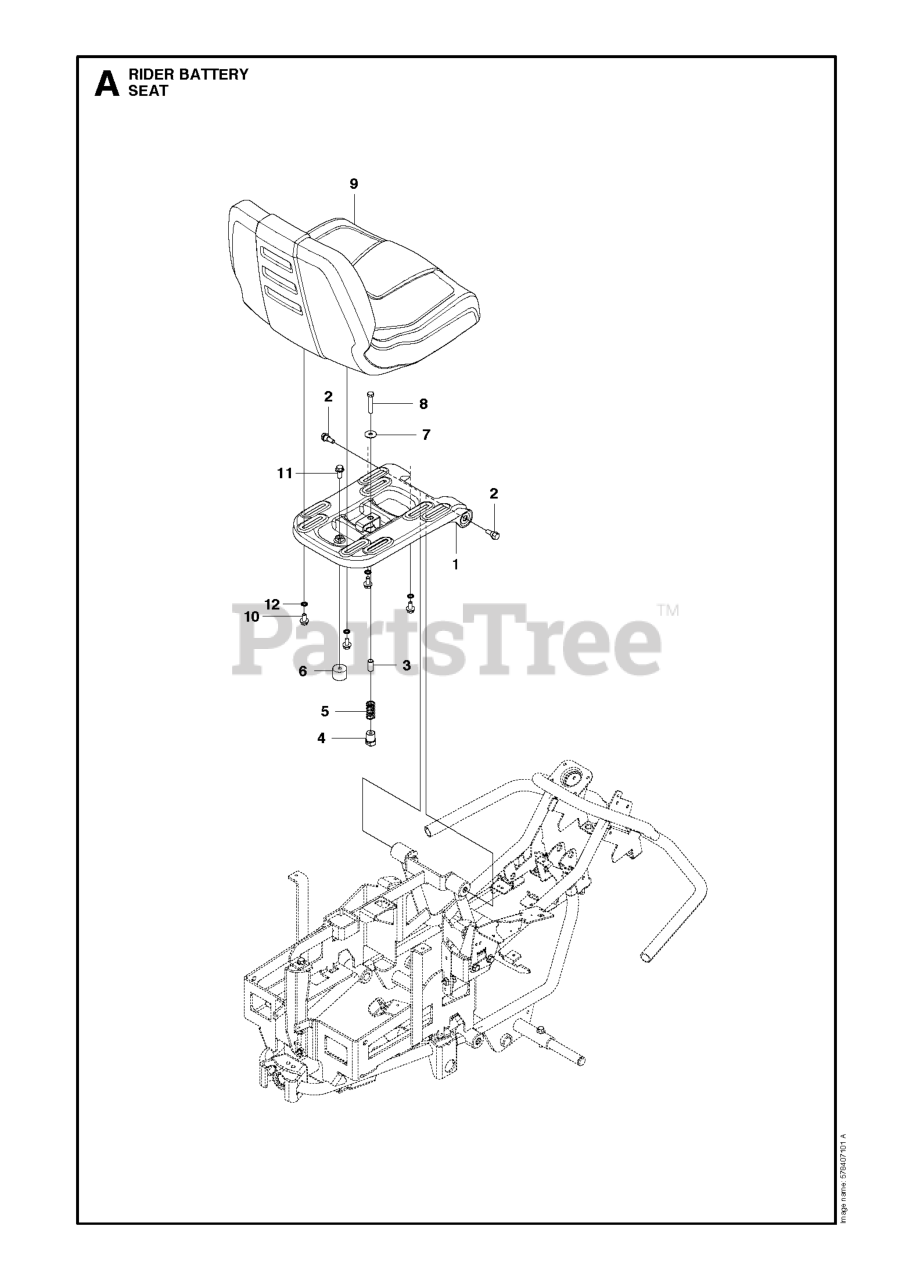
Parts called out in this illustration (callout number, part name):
3	SPACER TUBE
6	ANTIVIBRATION ELEMENT
8	SCREW
